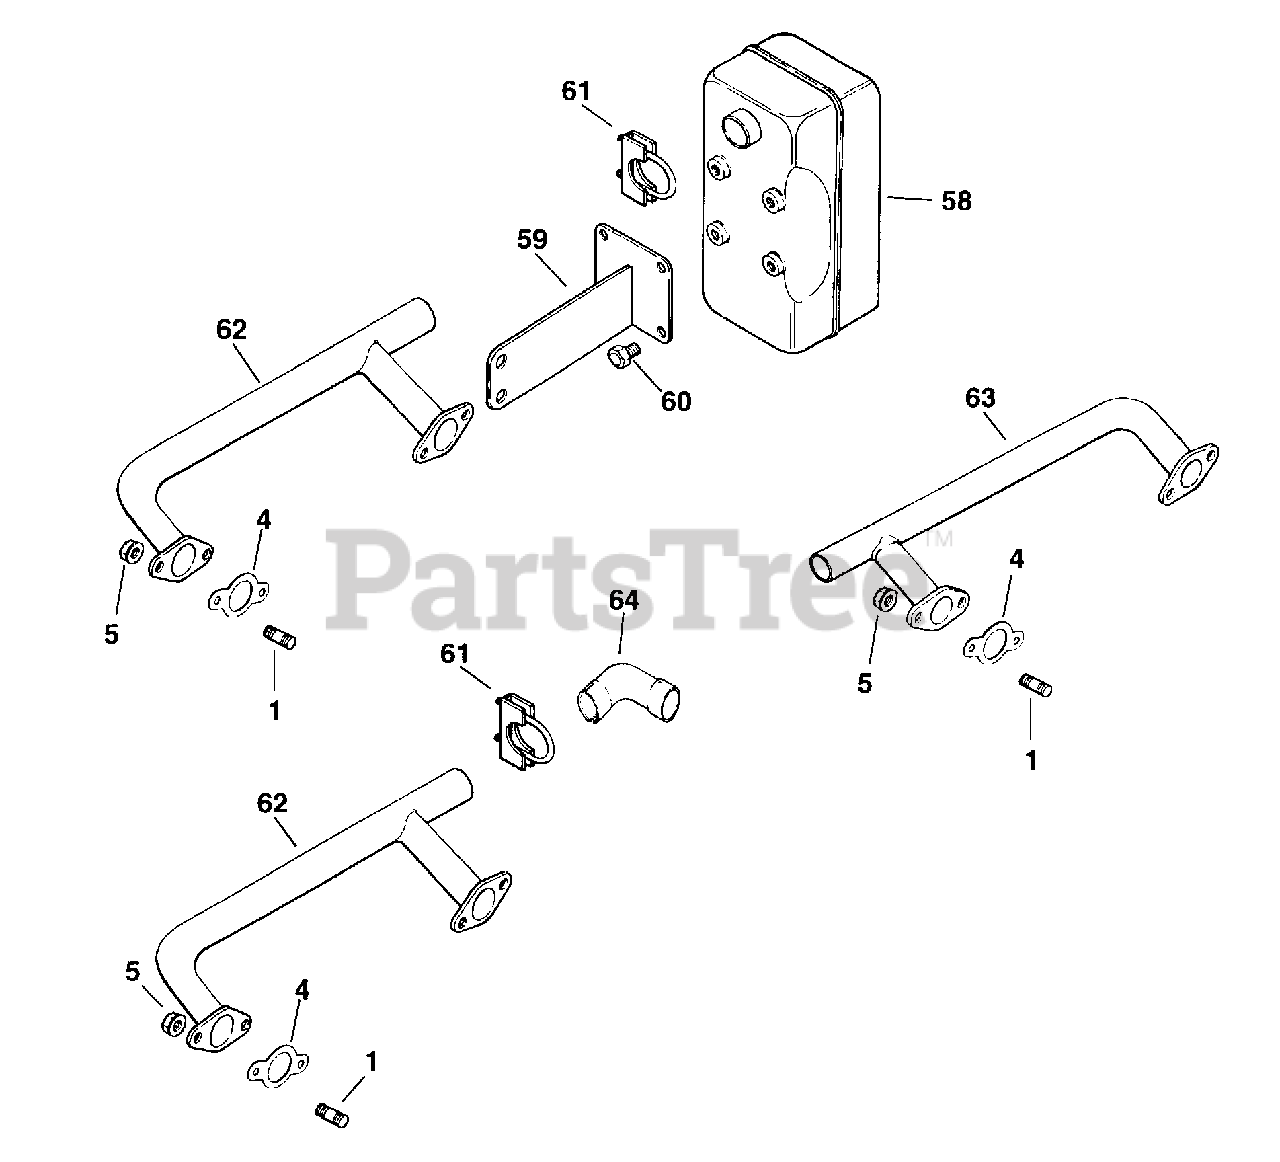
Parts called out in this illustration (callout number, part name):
1	STUD - USE M-829033
5	NUT - USE M-841080
62	MANIFOLD, EXHAUST 1 SIDE
